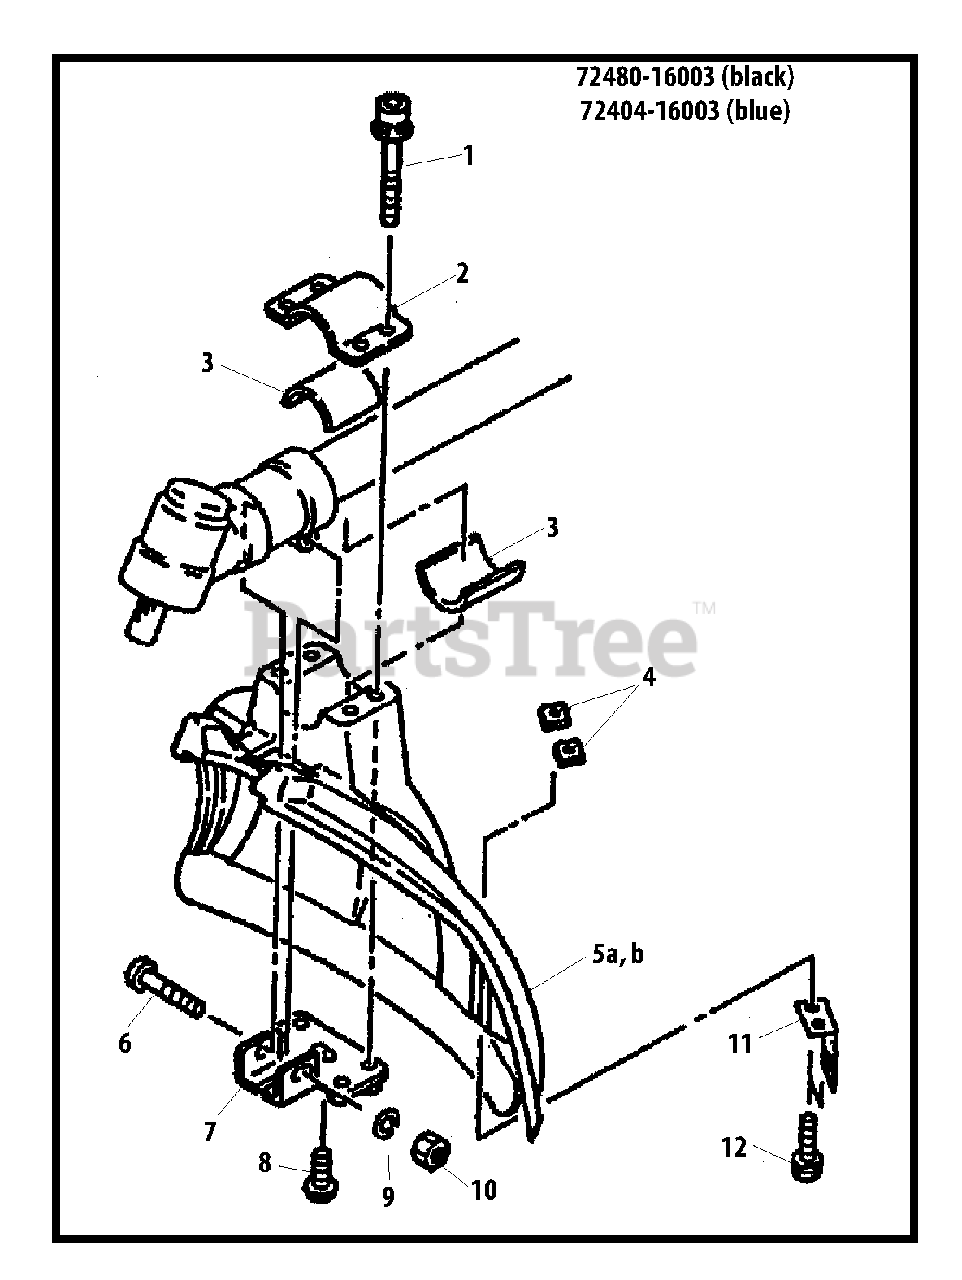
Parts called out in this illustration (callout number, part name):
1	SCREW - 5X45
2	CLAMP - UPPER
3	SPACER
4	NUT - 5
5A	SHIELD, DEBRIS - BLACK
5B	SHIELD, DEBRIS - BLUE
6	SCREW - 5X35
7	CLAMP - LOWER
8	SCREW
9	WASHER - 5
11	KNIFE, TRIMMER LINE
12	SCREW - 5X16
72404-16003	DEBRIS SHIELD KIT - BLUE
72480-16003	DEBRIS SHIELD KIT - BLACK
